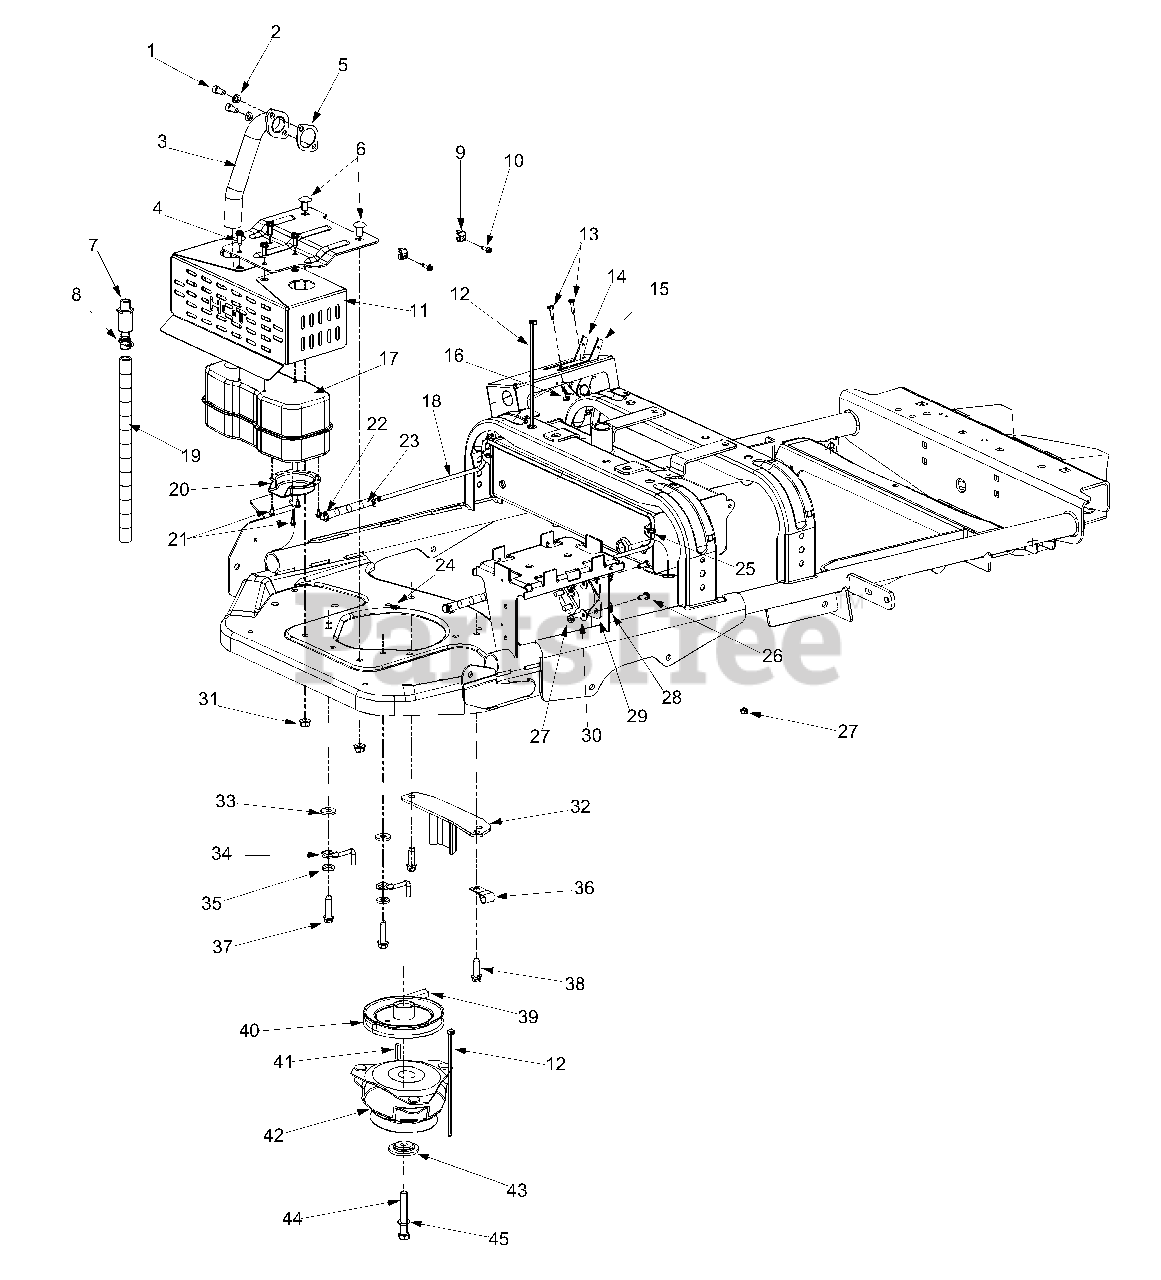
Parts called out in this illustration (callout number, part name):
1	Cap Screw 5/16-18
2	Lock Washer 5/16
3	Exhaust Pipe
4	Hex Washer Screw 1/4-20 x .75
5	Exhaust Gasket
6	Carriage Bolt 3/8-16 x .75
7	Oil Drain
8	Oil Drain Cap
9	Throttle Clamp
10	Hex Washer Screw #10-32 x .625
13	Screw #10-24 x .75
14	Throttle Cable Control 32"
15	Choke Cable Control 32.25"
16	Hex Lock Nut #10 - 24
17	Muffler
19	Oil Drain Hose
20	Muffler Deflector
21	Hex Washer Screw #8-32 x .375
23	Fuel Line Hose
24	Lock Washer 5/16
25	Retainer Clip
26	Hex Cap Screw 1/4-20 x .620
27	Hex Lock Nut 1/4-20
28	Lock Washer 1/4 ID x 3/4 OD
29	Solenoid
30	Bell Washer .265 ID x .75 OD
31	Flange Lock Nut 3/8-16
34	Rear Belt Retainer Rod
35	Flat Washer .407 ID x .812 OD
36	Heat Shield Cable Clip
37	Hex Washer Screw 3/8-16 x 1.5
38	Hex Washer Screw 3/8-16 x 1.25
39	V-Belt
40	Pulley
42	Electric Clutch
43	Spacer Clutch
44	Hex Cap Screw 7/16-20 x 3.0
45	Lock Washer 7/16
